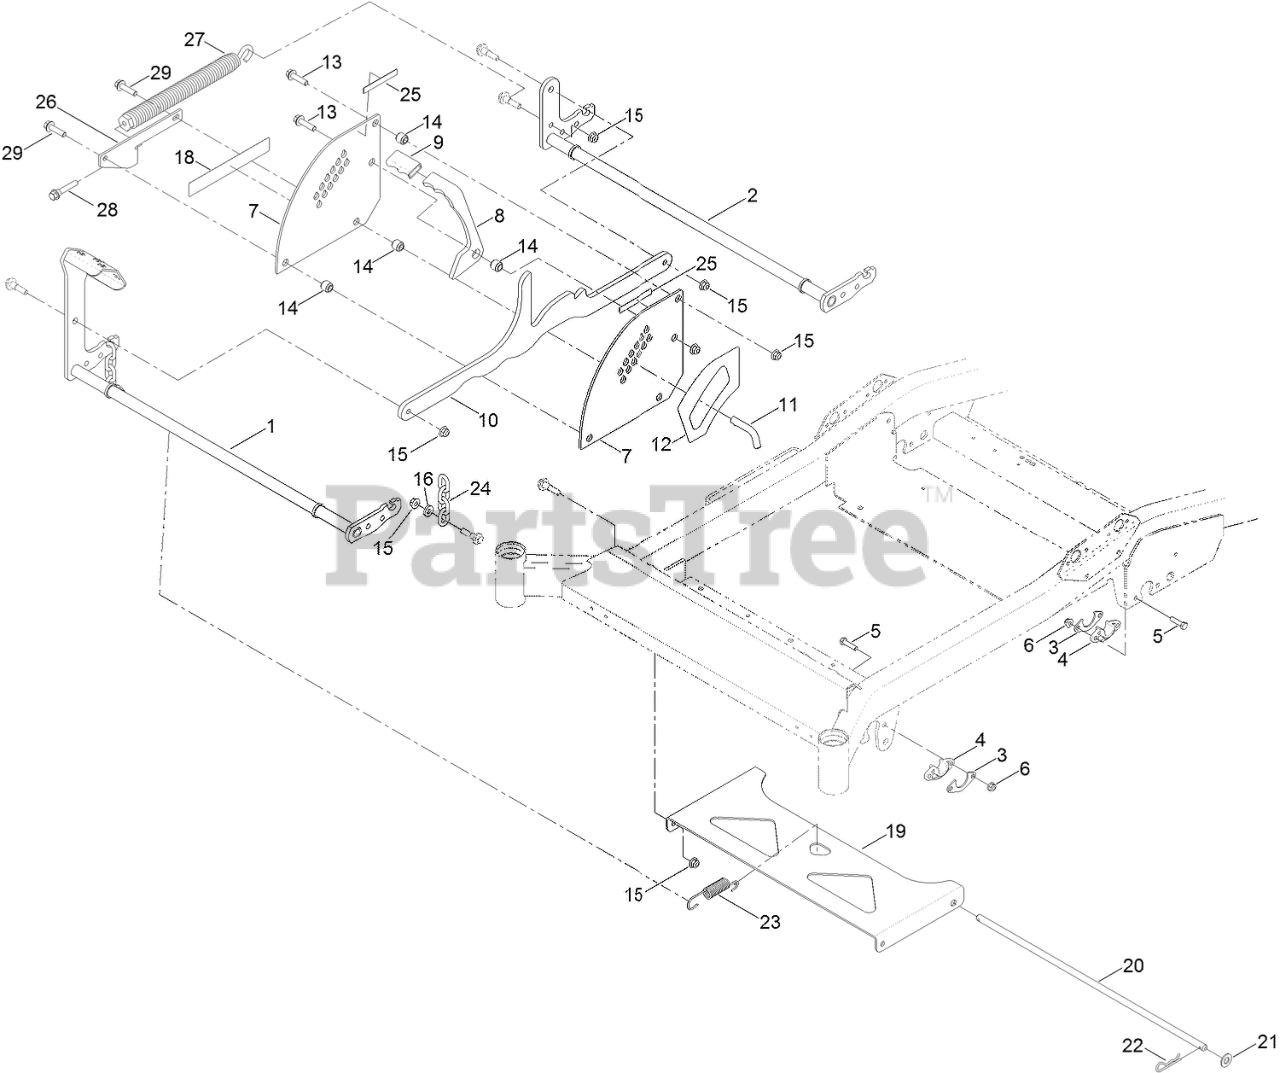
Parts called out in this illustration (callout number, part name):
1	PIVOT-FRONT
2	PIVOT-REAR
3	GUSSET-LIFT, DECK
4	BUSHING-FLANGE
5	SCREW-HH
6	NUT-HF, NI
7	PLATE-DECK, LIFT
8	LOCK-TRANSPORT, HOC
9	GRIP-FLAT
10	LINK-HOC
11	PIN-HOC
12	DECAL-HOC
13	SCREW-HHF
14	SPACER-STEP, DOUBLE
15	NUT-HF, NI
16	SPACER
19	PAN-DECK, PIVOT
20	ROD-DECK, PIVOT
21	WASHER-FLAT
22	PIN-COTTER
23	SPRING-EXTENSION
24	CHAIN-DECKLIFT
25	PAD-RUBBER
26	SUPPORT-SPRING
27	SPRING-EXTENSION
28	BOLT-SHOULDER
29	SCREW-HHF
